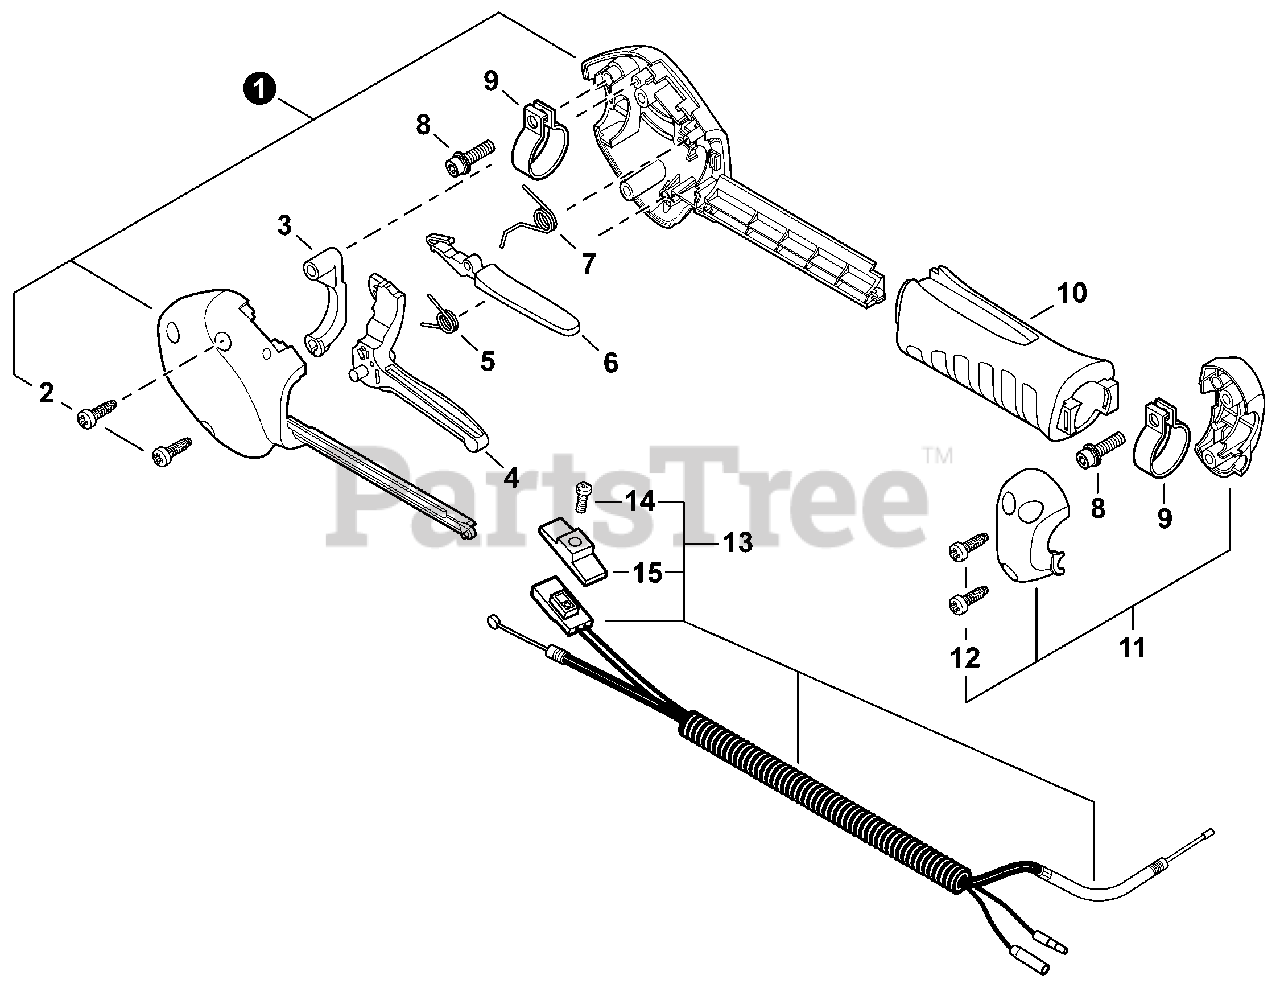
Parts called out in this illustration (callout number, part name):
1	HANDLE KIT, CONTROL
3	LOCKOUT, THROTTLE
4	TRIGGER, THROTTLE
5	SPRING, TORSION
6	LEVER, THROTTLE LOCKOUT
7	SPRING, TORSION
8	BOLT 5×20
10	GRIP, HANDLE
11	FIXTURE SET, HANDLE
13	CABLE ASSY, CONTROL
14	SCREW 3×10
15	KNOB, SWITCH - ORANGE
